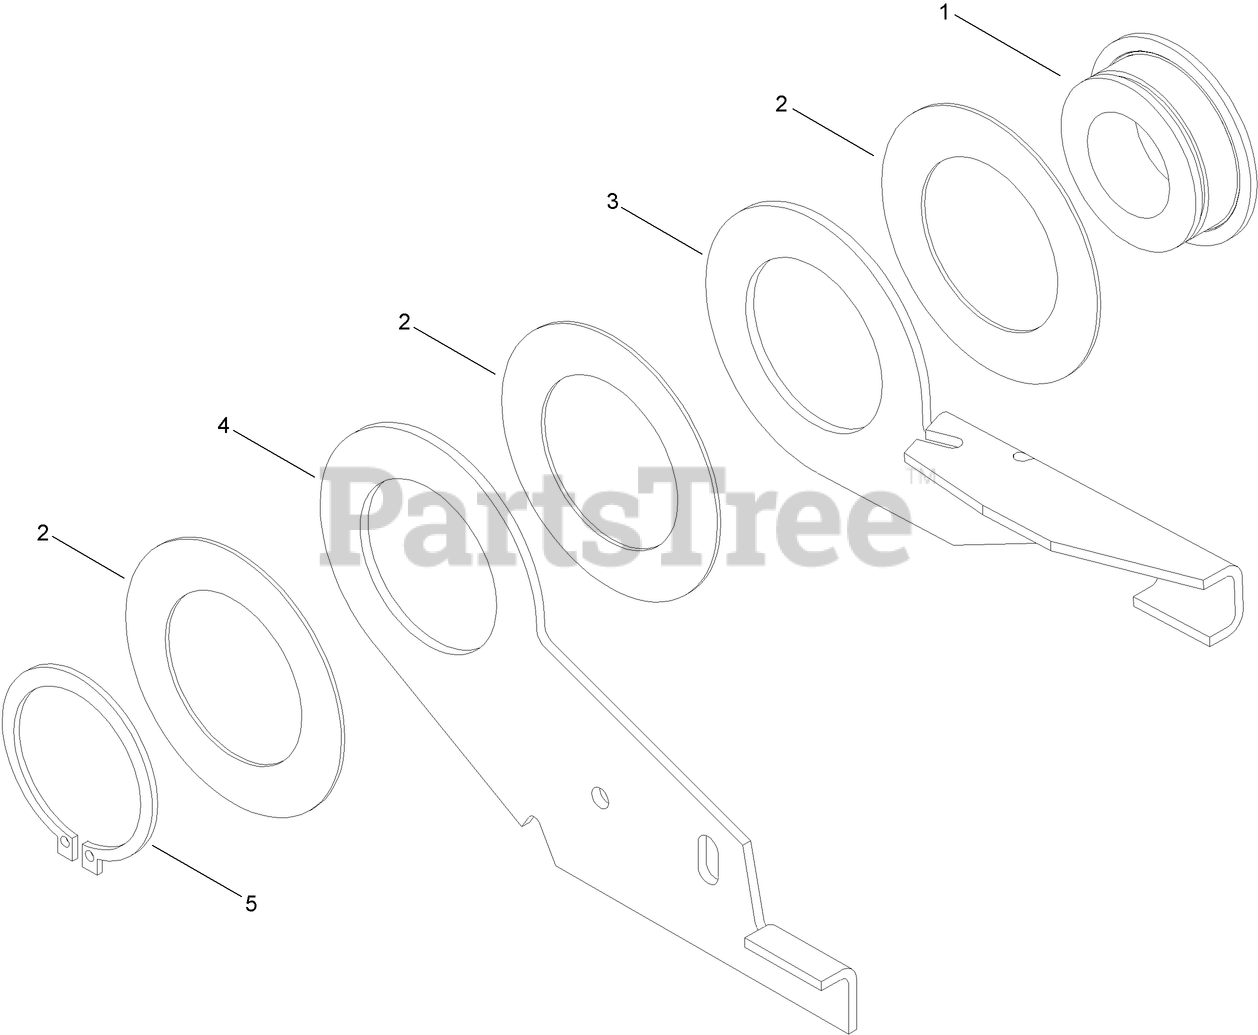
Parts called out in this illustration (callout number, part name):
3	PLATE-MOUNTING, SWITCH
4	PLATE-MOUNTING, SWITCH
5	RING-RETAINING
